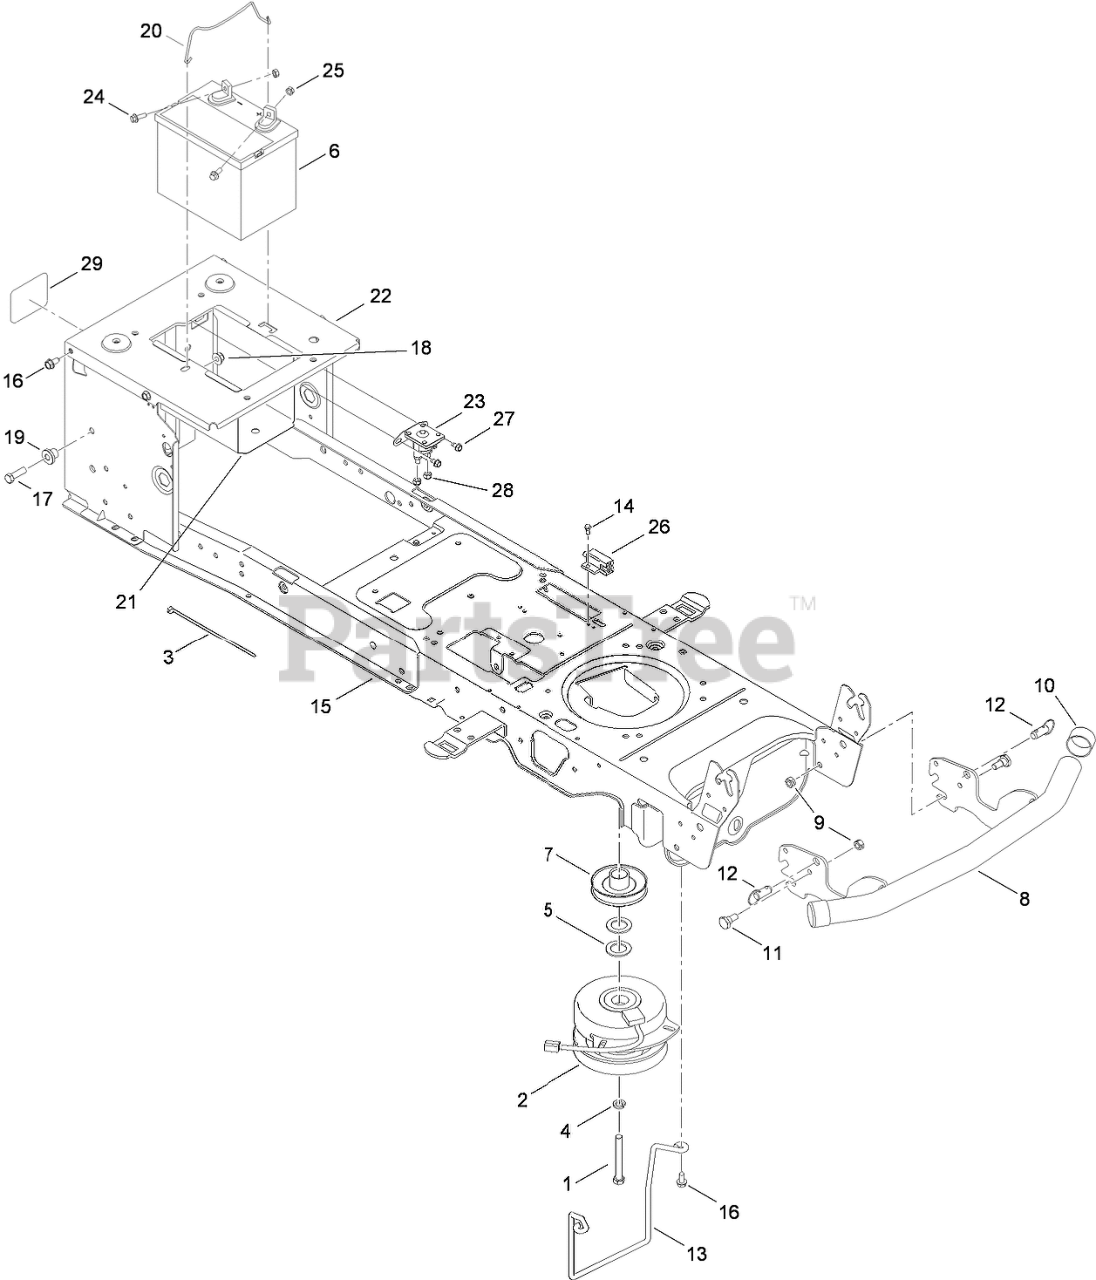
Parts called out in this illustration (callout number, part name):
1	SCREW-HH
2	CLUTCH-PTO, ELECTRIC
3	TIE-CABLE
4	WASHER-LOCK
5	WASHER-FLAT
6	BATTERY-245, CCA (DRY FLAT TOP)
7	PULLEY-ENGINE
8	BUMPER-UNIVERSAL
9	NUT-LOCK
10	CAP-HUB
11	BOLT-SHOULDER
12	PIN-RELEASE, QUICK
13	ROD-KEEPER
14	BOLT-SHOULDER
15	LOWER FRAME ASM
16	SCREW-TAP
17	SCREW-HH
18	NUT-LOCK, FLANGE
19	SPACER-SHOULDER
20	ROD-HOLDDOWN, BATTERY
21	TRAY-BATTERY
22	BRACKET-FRAME, SEAT
23	SOLENOID-12V, 2 POST 2 Tab
25	NUT-SEMS
26	SWITCH-INTERLOCK, NO/NC
27	SCREW-TAP
28	NUT-LOCK, FLANGE
29	DECAL-RELEASE
